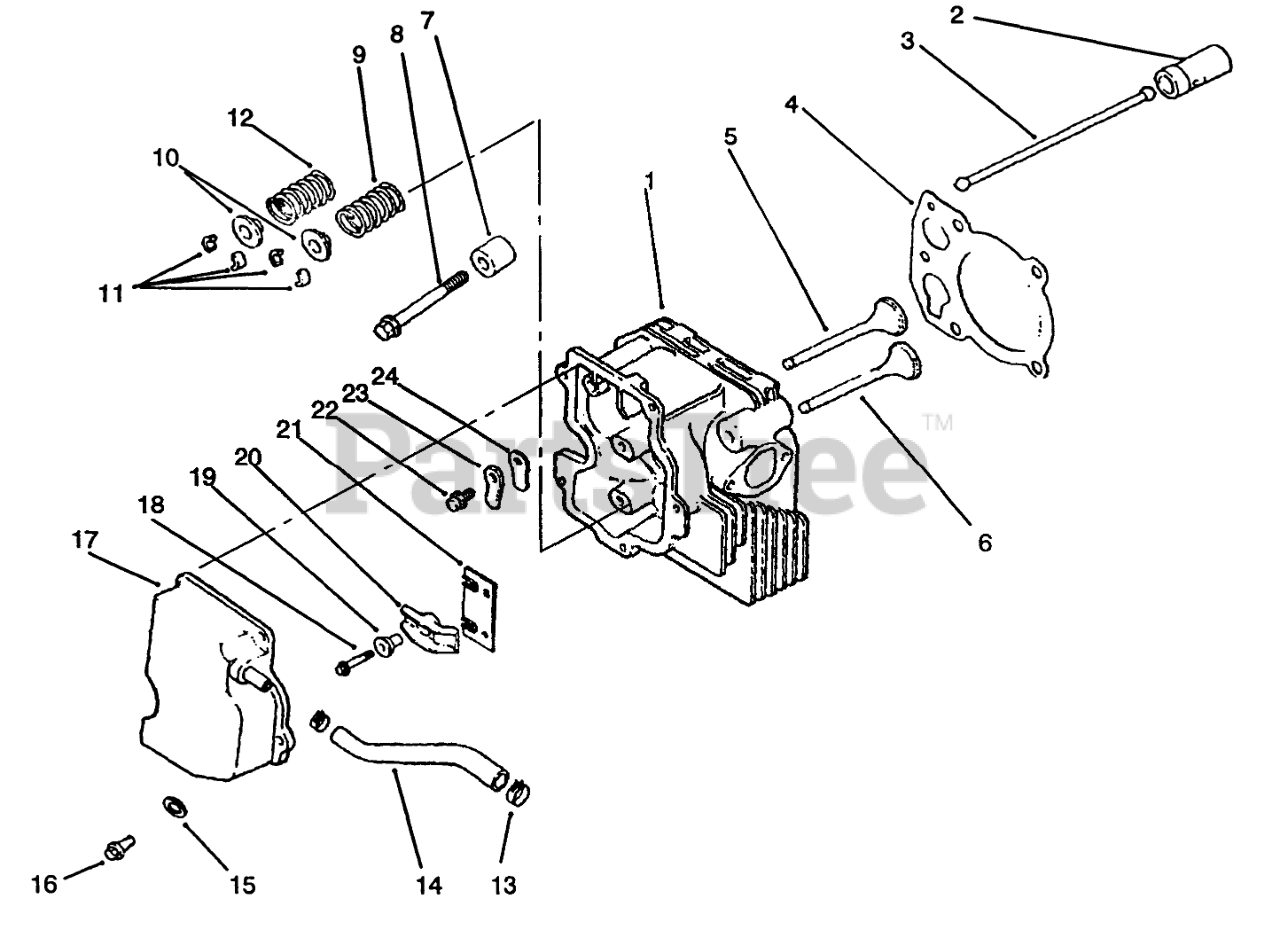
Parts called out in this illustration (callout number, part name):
1	Cylinder Head (Only On: 72042, 72063, 72062, 72043)
2	Lifter-Valve (Only On: 7 2042, 72063, 72062, 72043)
3	Rod-Push (Only On: 72042, 72063, 72062, 72043)
4	Gasket-Cylinder Head (Only On: 72042, 72063, 72062, 72043)
5	Valve-Intake STD (Only On: 72042, 72063, 72062, 72043)
5	Valve-Intake .25 (Only On: 72043, 72042, 72063, 72062)
6	Valve-Exhaust STD (Only On: 72042, 72063, 72062, 72043)
6	Valve-Exhaust .25 (Only On: 72042, 72063, 72062, 72043)
7	Spacer-Head Bolt Exhaust (Only On: 72042, 72063, 72062, 72043)
8	Screw M10x1.5x80 (Only On: 72042, 72063, 72062, 72043)
9	Spring-Valve Exhaust (Only On: 72042, 72063, 72062, 72043)
10	Cap-Valve Spring (Only On: 72042, 72063, 72062, 72043)
11	Kit-Retainer (Only On: 72042, 72063, 72062, 72043)
12	Spring-Valve Intake (Only On: 72042, 72063, 72062, 72043)
13	Clamp-Hose (Only On: 72042, 72063, 72062, 72043)
14	Hose-Breather (Only On: 72042, 72063, 72062, 72043)
15	Washer-Flat (Only On: 72042, 72063, 72062, 72043)
16	Screw M6x1.0x20 (Only On: 72042, 72063, 72062, 72043)
17	Cover-Valve W/Nipple (Only On: 72042, 72063, 72062, 72043)
18	Screw M6x1.0x34 (Only On: 72042, 72063, 72062, 72043)
19	Ball-Rocker Pivot (Only On: 72042, 72063, 72062, 72043)
20	Arm-Rocker (Only On: 72042, 72063, 72062, 72043)
21	Plate-Guide (Only On: 72042, 72063, 72062, 72043)
22	Screw M5x0.8x10 (Only On: 72042, 72063, 72062, 72043)
23	Retainer-Breather Reed (Only On: 72042, 72063, 72062, 72043)
24	Reed-Breather (Only On: 72042, 72063, 72062, 72043)
